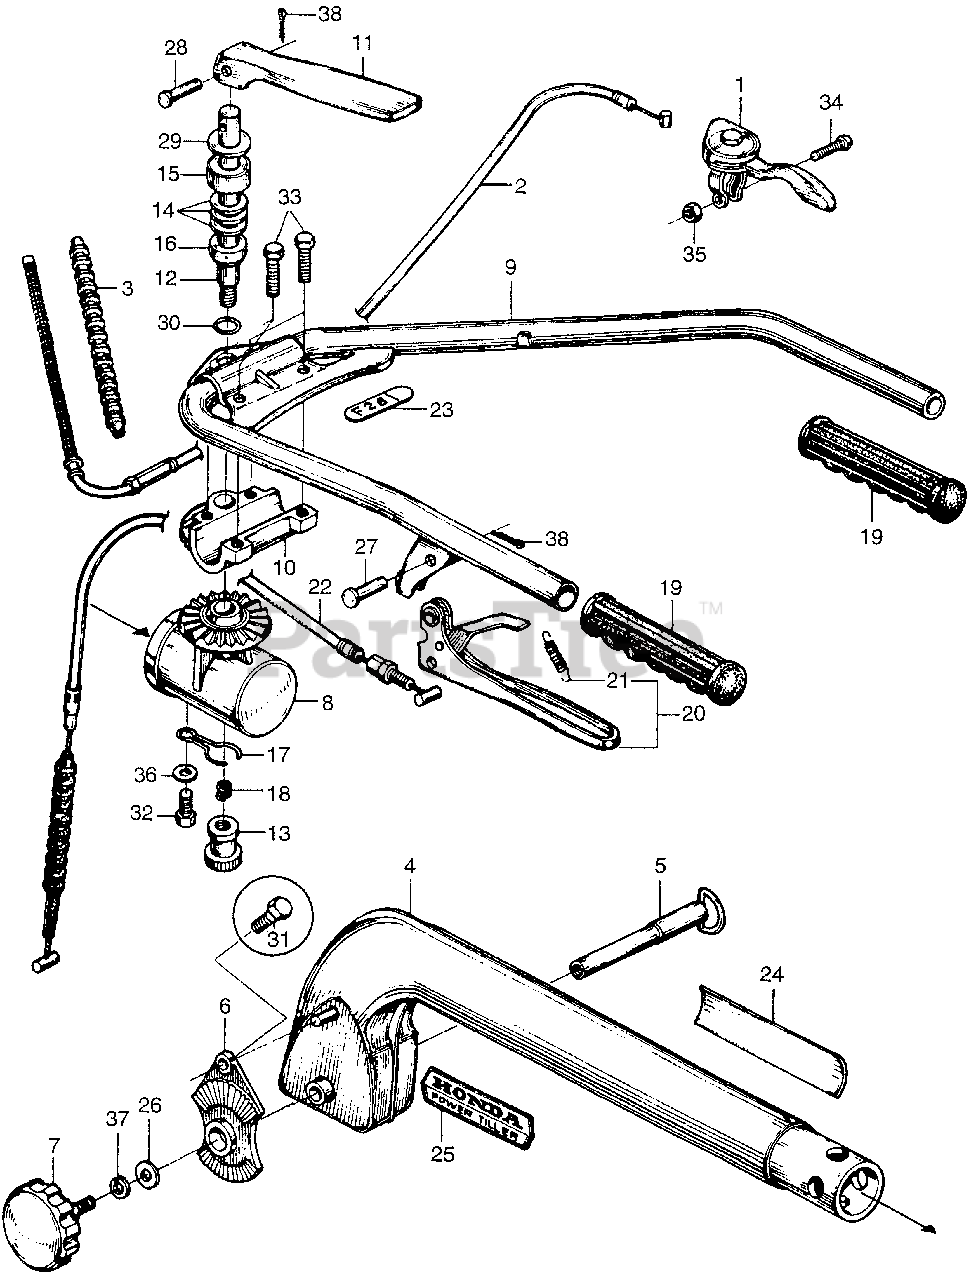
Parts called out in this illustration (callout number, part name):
1	LEVER, THROTTLE
1	LEVER ASSY., THROTTLE
2	CABLE, THROTTLE (NOT AVAILABLE)
3	BOLT, WIRE
4	COLUMN, HANDLE *R8* (BRIGHT RED)
5	SHAFT, HINGE
6	SWINGARM (NOT AVAILABLE)
7	ADJUSTER A, HANDLE (NOT AVAILABLE)
8	BASE, SWING (NOT AVAILABLE)
9	HANDLEBAR (NOT AVAILABLE)
10	FRAME, SWING HANDLE
11	LEVER, HANDLE ADJUSTING
12	SHAFT, HANDLE ADJUSTING
13	NUT, HANDLE ADJUSTING
14	SPRING, HANDLE ADJUSTING
15	SHEET, HANDLE ADJUSTING SPRING
16	COLLAR, ADJUSTING
17	HOLDER, NUT
18	SPRING, LOCK
19	GRIP, HANDLE
20	LEVER, CLUTCH (NOT AVAILABLE)
21	SPRING, LEVER (NOT AVAILABLE)
22	CABLE, CLUTCH
23	MARK C (NOT AVAILABLE)
24	PLATE, CAUTION (NOT AVAILABLE)
25	EMBLEM, HANDLE COLUMN
26	WASHER B, SEALING (10MM)
27	PIN (8X18)
28	PIN, ARM (NOT AVAILABLE)
29	WASHER, THRUST (14)
30	O-RING (58.5X2)
32	BOLT, HEX. (6X12)
33	BOLT, HEX. (6X16)
34	SCREW, PAN (5X20)
35	NUT, HEX. (5MM)
36	WASHER, PLAIN (6MM)
37	WASHER, SPRING (8MM)
38	PIN, COTTER (2.0X15)
